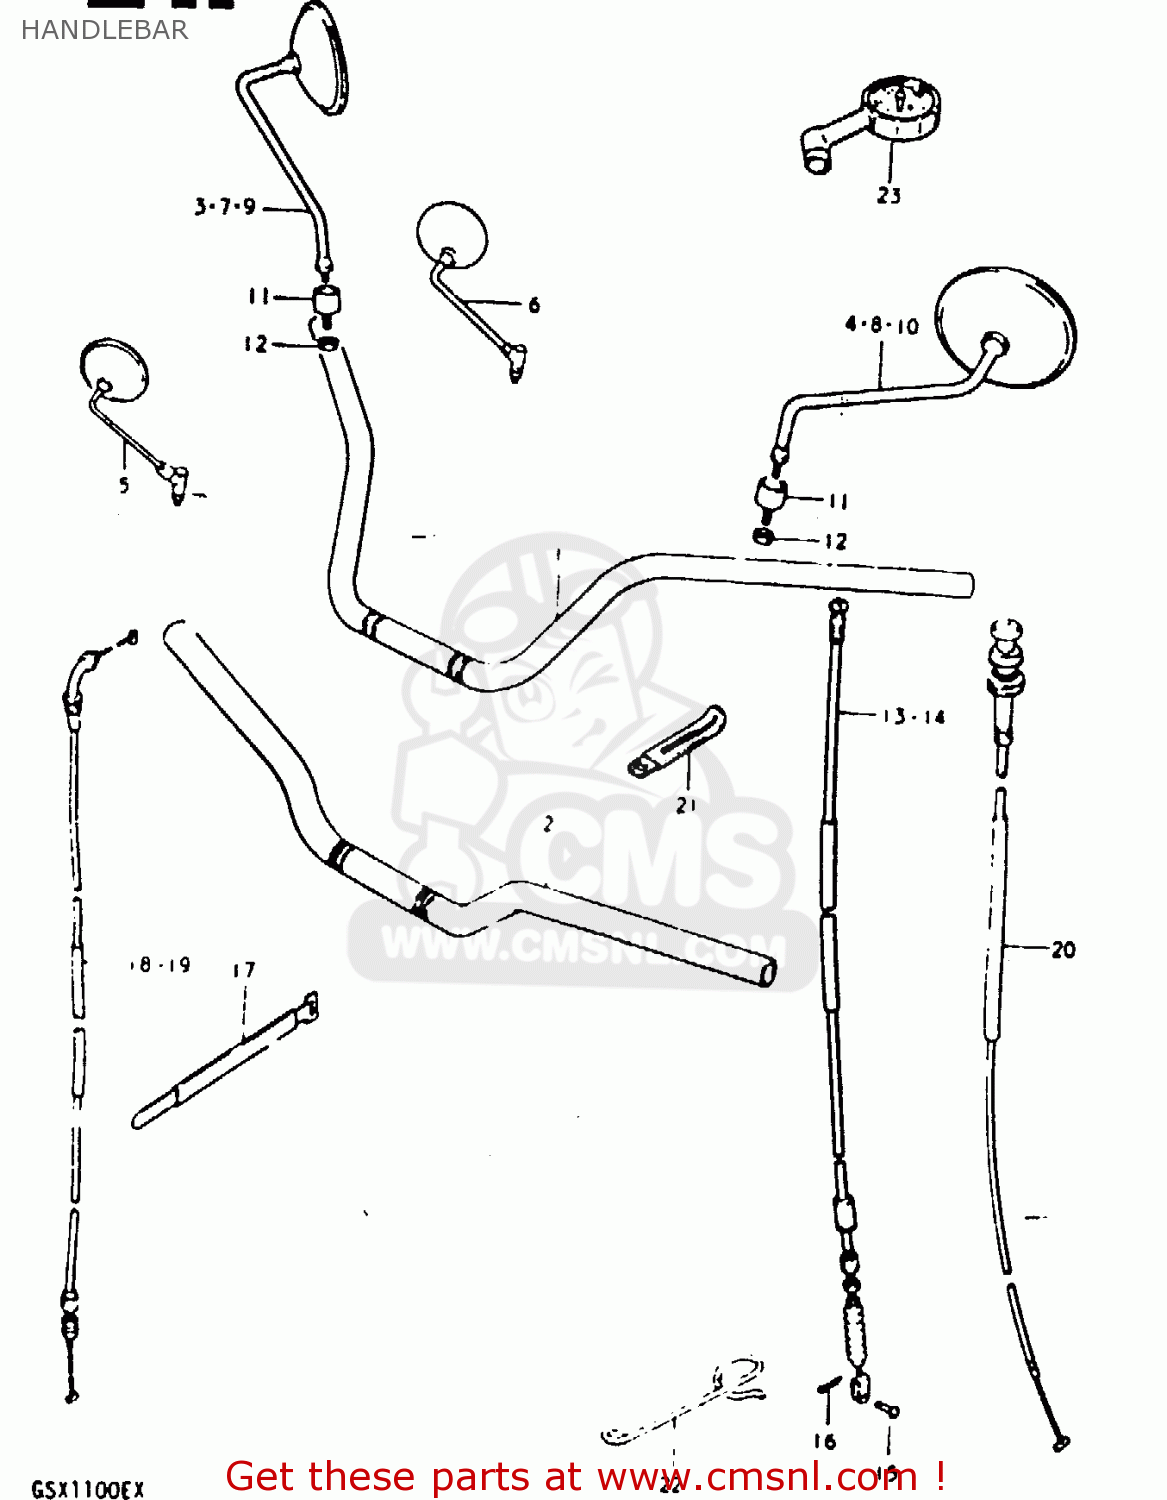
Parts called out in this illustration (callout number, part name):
1	HANDLEBAR
2	HANDLEBAR
3	MIRROR ASSEMBLY,RIGHT
4	MIRROR ASSEMBLY,LEFT
5	MIRROR ASSY,RR VIEW
11	CUSHION,REAR VIEW MIRROR
12	NUT
13	CABLE ASSEMBLY,CLUTCH
14	CABLE, CLUTCH (FLAT TYPE)
15	PIN(L:15)
16	PIN
17	CLAMP
18	CABLE ASSEMBLY,THROTTLE
19	CABLE ASSEMBLY,THROTTLE
20	CABLE ASSEMBLY,STARTER
21	CLAMP
22	GUIDE,CLUTCH CABLE
23	GAUGE ASSY,AIR PRESSURE
